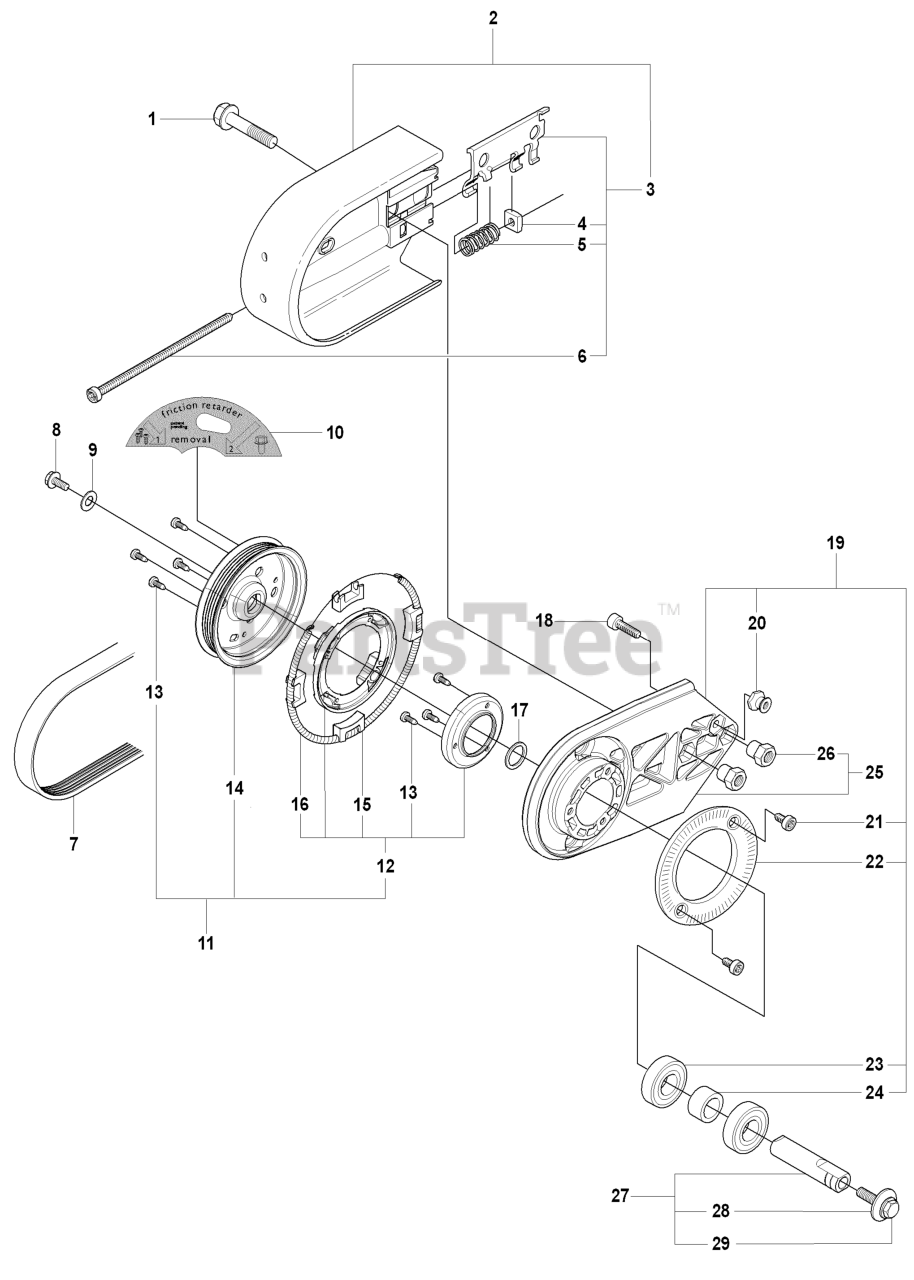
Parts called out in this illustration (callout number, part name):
2	BELT GUARD
3	TENSIONER
7	BELT MICRO V 12-14"
7	BELT MICRO V 16"
11	PULLEY
12	PULLEY
14	%PULLEY
15	RP BRAKE SHOE
16	DRAW SPRING
17	WASHER 15X21
18	SCREW MC6S 5X16
19	HOUSING
23	BALL BEARING
25	HOUSING
27	SHAFT
28	WASHER
29	SCREW
